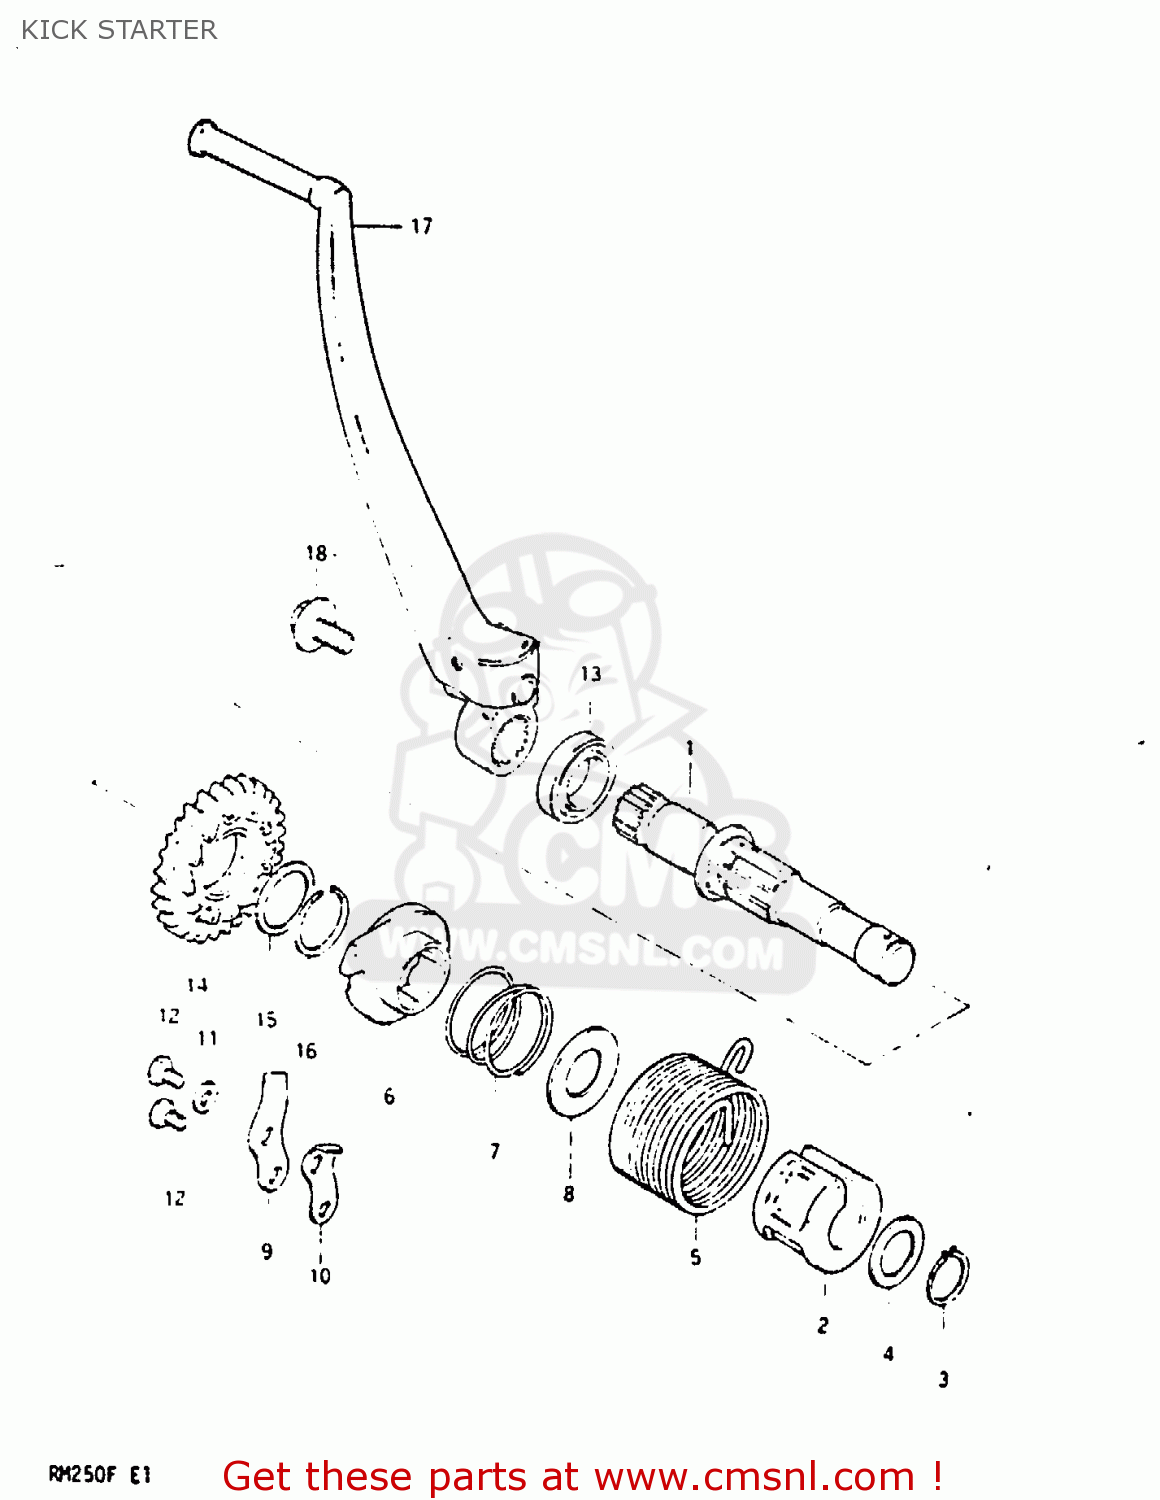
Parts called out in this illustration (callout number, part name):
1	SHAFT,KICK STARTER
2	GUIDE,KICK STARTER SFT SPRING
3	CIRCLIP
4	WASHER
5	SPRING
6	STARTER,KICK
7	SPRING
8	WASHER
9	GUIDE,KICK STARTER
10	STOPPER,KICK STARTER
11	WASHER
12	BOLT
13	SEAL,OIL(20X27X5)
14	GEAR
15	SHIM
16	CIRCLIP
17	LEVER ASSEMBLY,KICK STARTER
18	BOLT(8X14)
